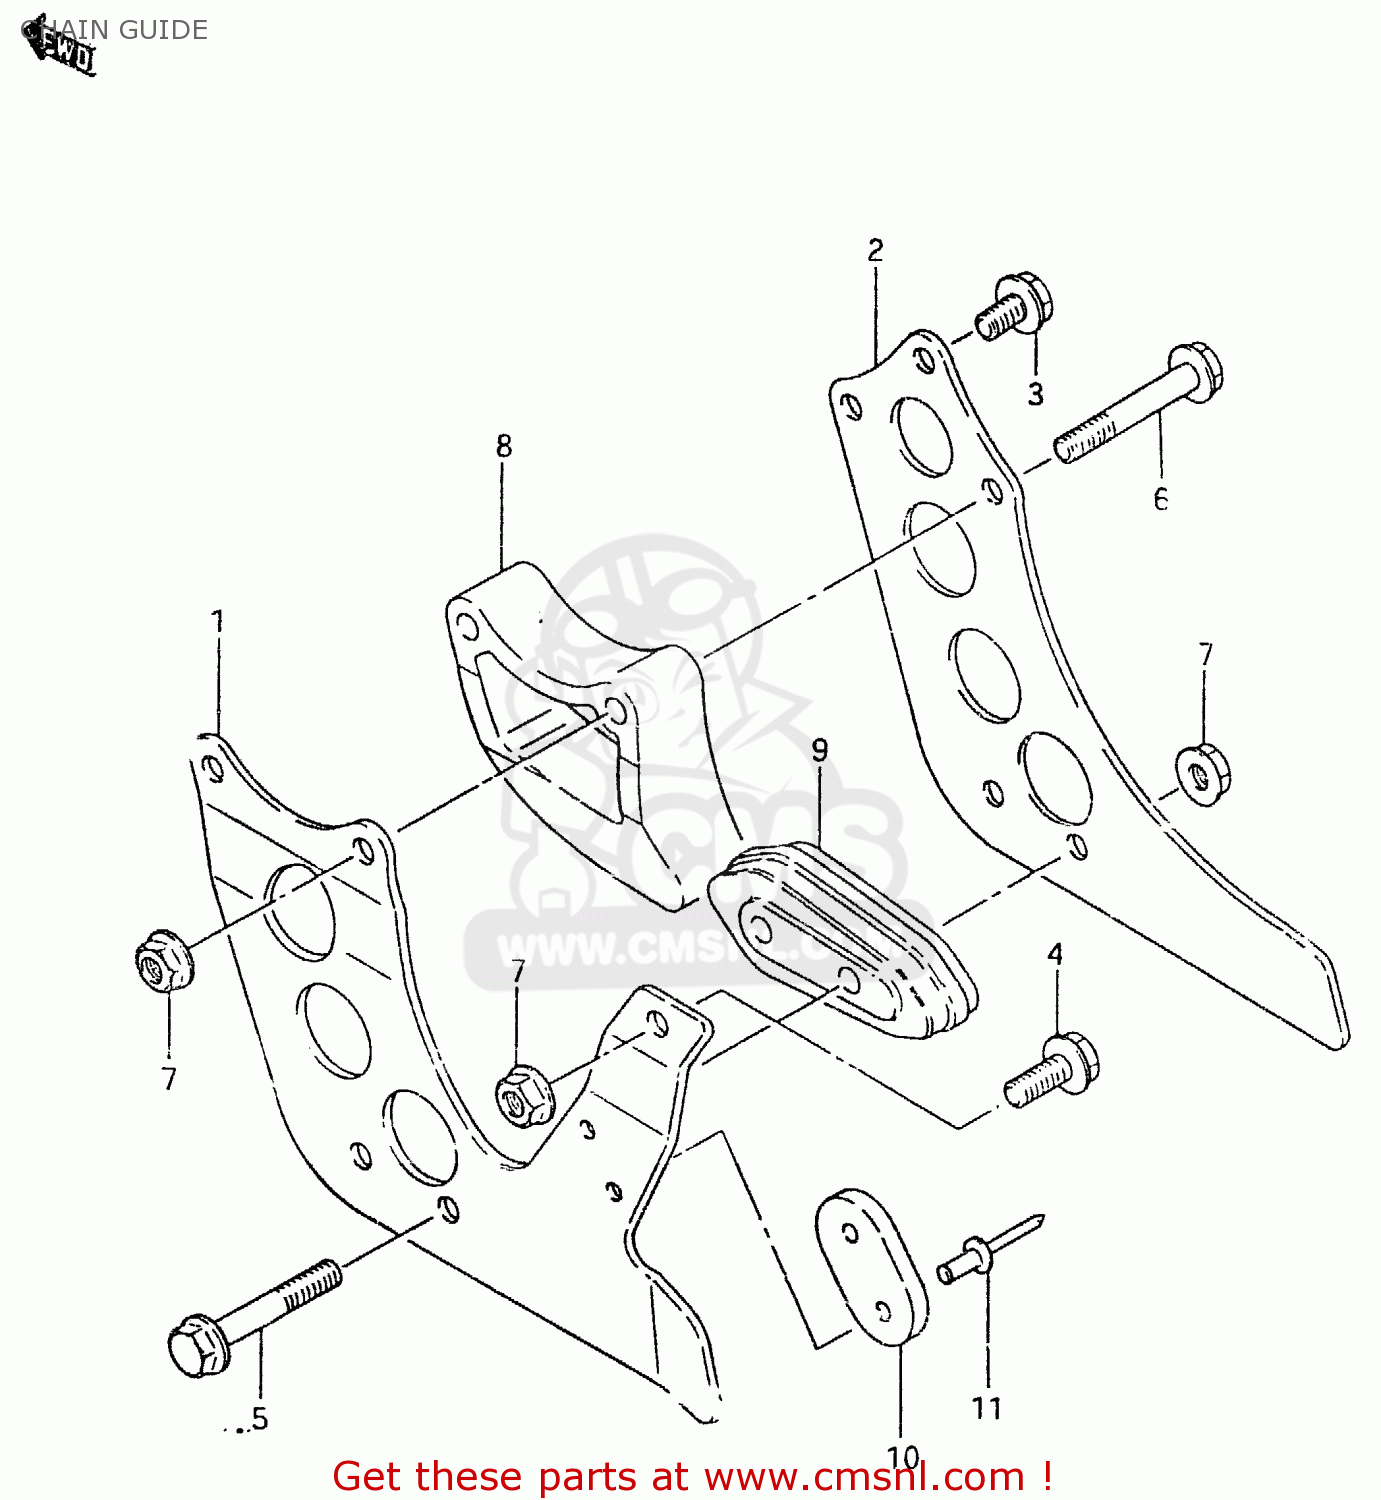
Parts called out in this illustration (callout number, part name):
1	PLATE,CHAIN GUIDE,OUTER
2	PLATE,GUIDE CHAIN
3	BOLT
4	BOLT
5	BOLT
6	BOLT,UNDER
7	NUT
8	DEFENSE,CHAIN GUIDE UPR
9	DEFENSE,CHAIN GUIDE
10	PAD,DRIVE CHAIN GUIDE
11	RIVET
